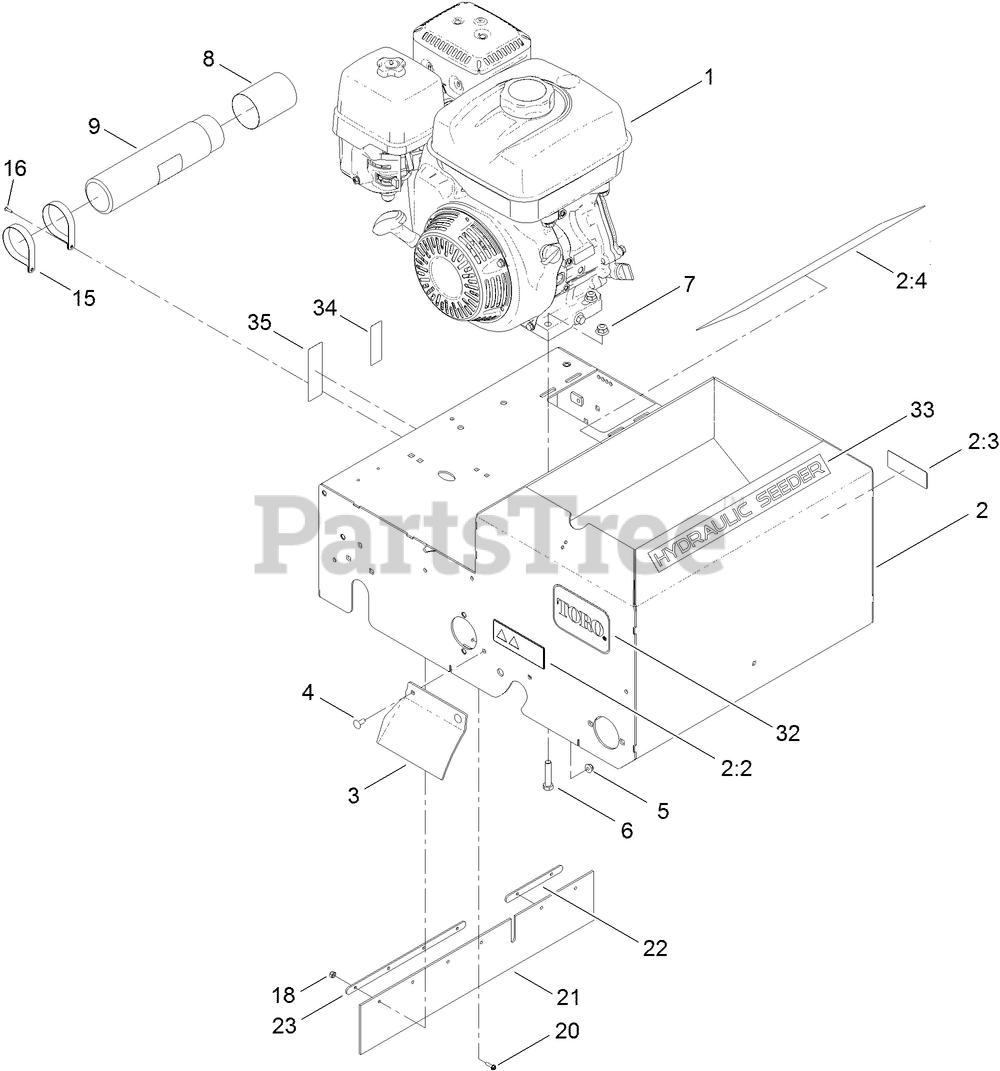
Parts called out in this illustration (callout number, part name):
2	FRAME ASM
2:2	DECAL-DANGER
2:3	DECAL-WARNING, SHIELDS
2:4	DECAL-WARNING
3	GUARD-RH
4	SCREW-CARR
5	NUT-HF
6	SCREW-HH
7	NUT-HF, NI
8	CAP-HOUSING
9	TUBE-MANUAL
15	CLAMP-R
16	RIVET-POP
18	NUT-LOCK
20	SCREW-SHH
21	GUARD-DUST
22	PLATE-RETAINER
23	PLATE-RETAINER
32	DECAL
34	DECAL-BRAKE, PARKING
35	DECAL-BYPASS
